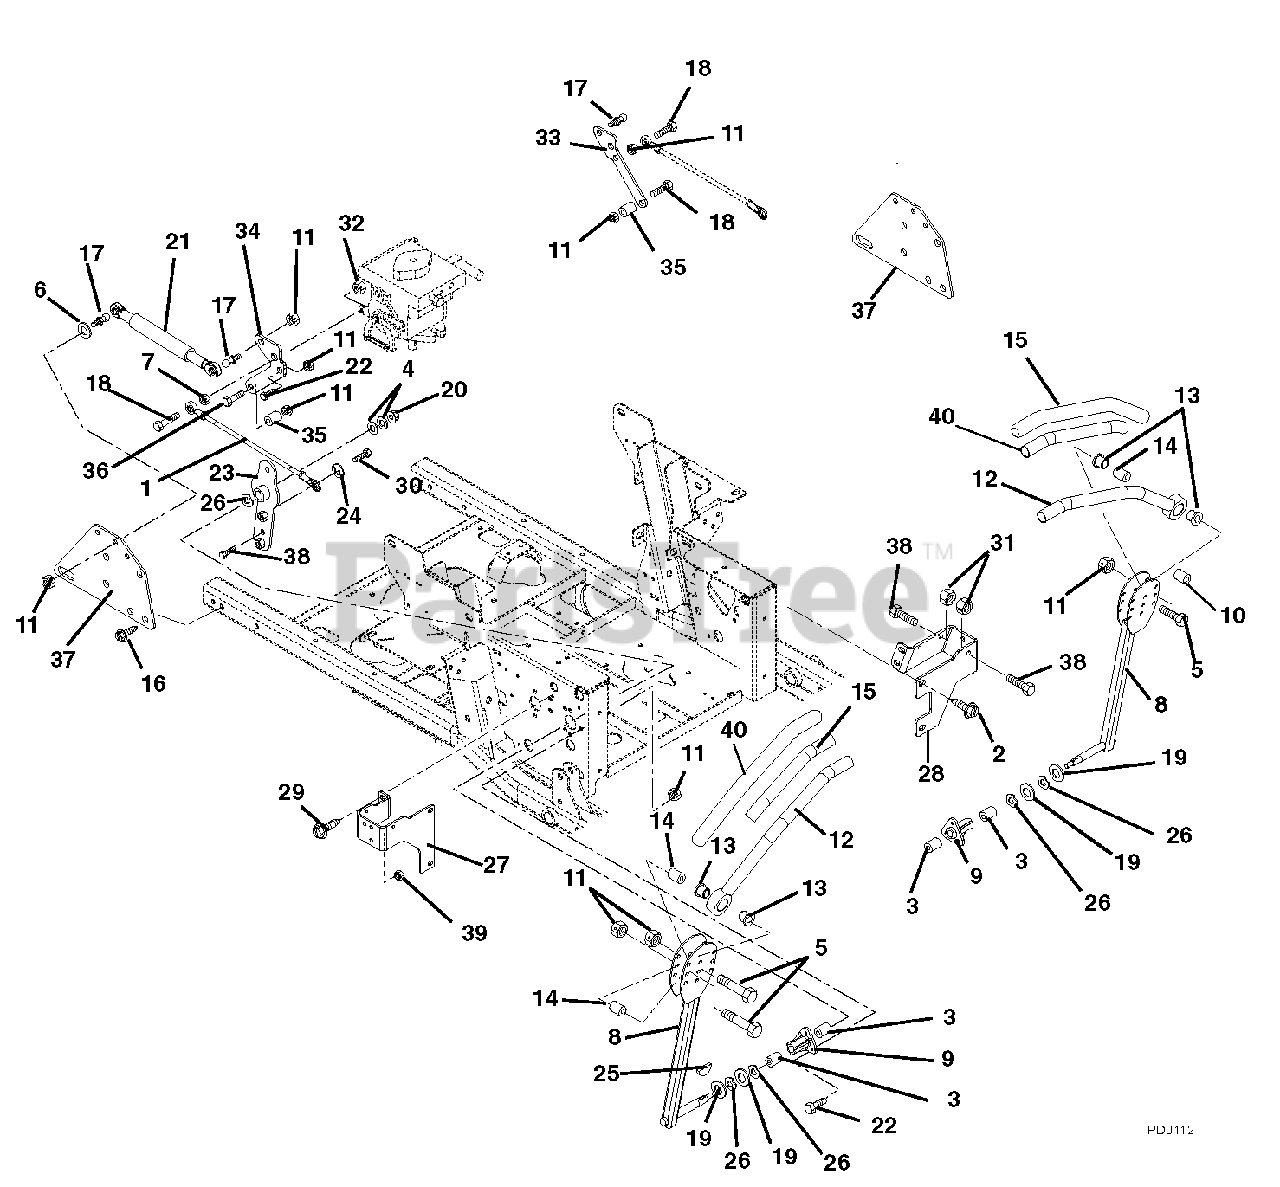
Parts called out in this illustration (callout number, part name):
1	Assembly, Steering Rod .38 Rod x 7.60
2	Screw, Tapping .38-16 x .75 Hex Washer Head
3	Bushing .625 x .75 x .50
4	Washer, Flat Steel .403 x .812 x .065
5	Bolt, Hex .31-18 x 1.75 Grade 5
6	Washer, Flat Steel .344 x .688 x .065
7	Nut, Hex .38-16
8	Control Arm
9	Bushing, Flange
10	Bushing, Eccentric .31 x .75 x .97
11	Nut, Locking Top Flange .31-18
12	Handle Weldment Left-Hand
13	Bushing, Flange Nylon .762 x 1.48 x .44
15	Grip, Handlebar
16	Screw, Tapping .31-18 x .50 Hex Washer Head
17	Stud, Ball
18	Bolt, Hex .38-16 x 1.50 Grade 5
19	Washer, Flat Steel .63 x 1.005 x .062
20	Nut, Locking Top Flange .38-16
21	Damper, Control
22	Bolt, Hex .31-18 x .75 Grade 5
23	Weldment, Pivot Arm
24	Washer, Locking .38 x .094 Regular
25	Key, Woodruff .13 x .63
26	Washer, Wave
27	Stop, Steering Right Hand
28	Stop, Steering Left Hand
29	Screw, Tapping .38-16 x .50 Hex Washer Head
30	Bolt, Hex .38-16 x 1.25 Grade 5
31	Nut, Hex Jam .375-16
32	Nut, Locking Center .38-16
33	Bracket, Left Hand
34	Bracket, Right Hand
35	Spacer .318 x .43 x .375
36	Bolt, Hex .31-18 x 1.25 Grade 5
37	Bracket, Damper
38	Bolt-Hex .375-16 x 1.75 Full Thread
39	Nut, Locking Top Flange .25-20
40	Tube, .88ID x 1.00OD x 10.75
